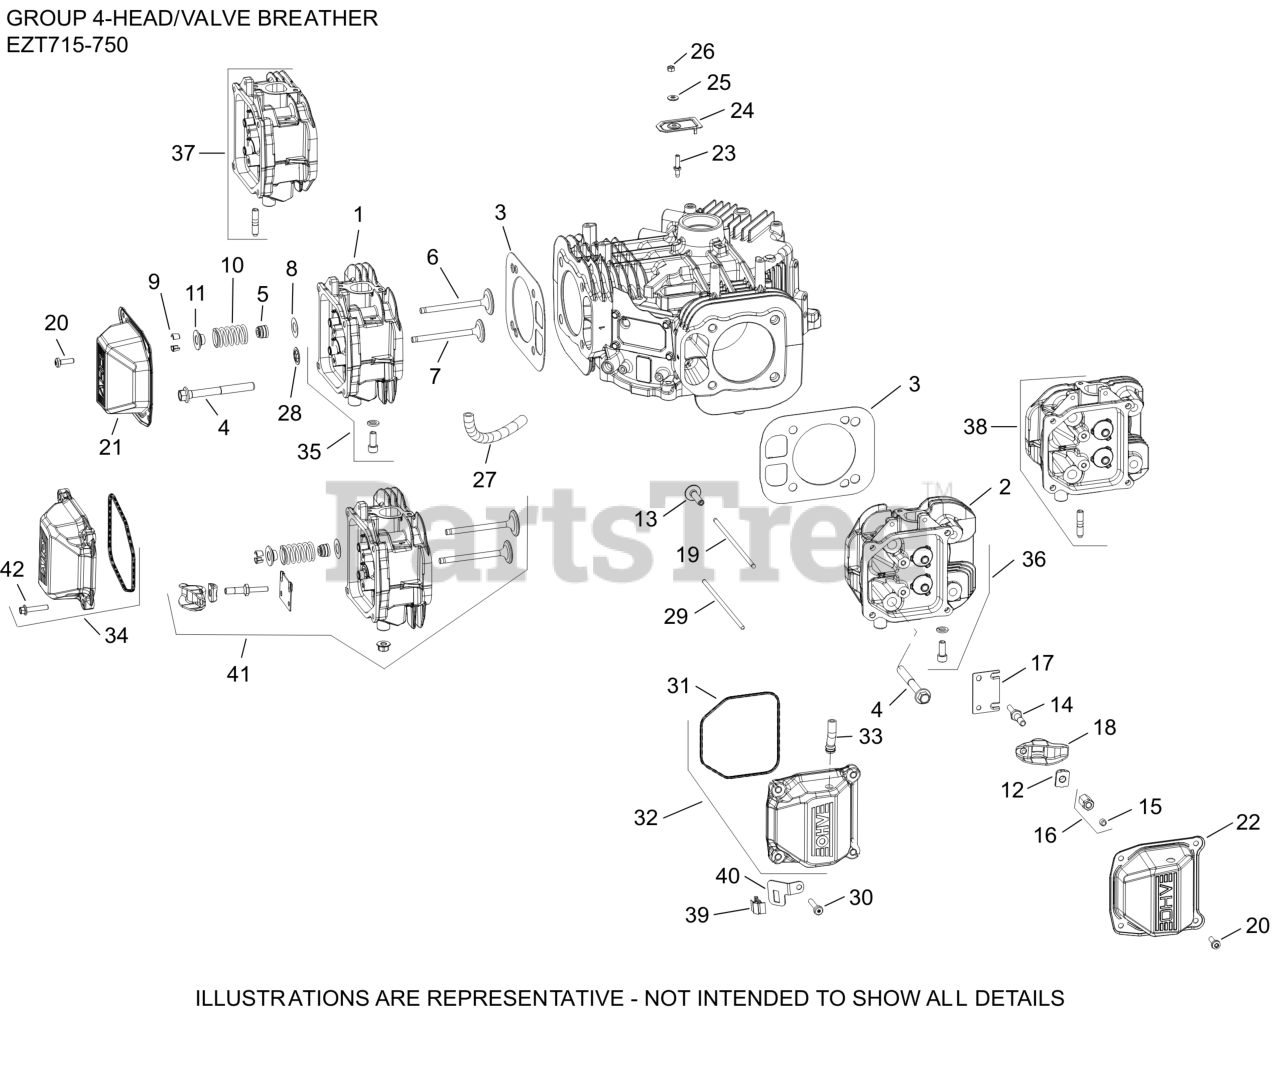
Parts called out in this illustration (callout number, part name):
3	KIT, GASKET CYLINDER HEAD
5	SEAL, VALVE BAND
7	VALVE, EXHAUST
7	VALVE, EXHAUST (.25)
8	SPACER (.010")
9	KIT, RETAINER
10	SPRING VALVE
11	CAP, VALVE SPRING
12	PIVOT, ROCKER ARM
14	STUD, ROCKER
15	SCREW, SET
16	HEX NUT ASSEMBLY
17	PLATE, GUIDE
18	ARM, ROCKER
19	ROD, PUSH
24	COVER, BREATHER REED
25	WASHER, SEALING
26	NUT, LOCK M5X.8
27	HOSE, BREATHER
28	RETAINER, VALVE GUIDE (KM)
31	O-RING (YELLOW), VALVE CO
32	KIT,BREATHER VALVE COVER (PLASTIC)
33	HOSE, FP-USE 32 326 07-S(PLASTIC COVERS)
34	KIT, VALVE COVER-PLAIN (PLASTIC)
36	KIT, HEAD #2 AND HARDWARE-(#1675521S)
41	KIT, CYLINDER HEAD #1
NI	VALVE, INTAKE (STD)
NI	VALVE, INTAKE (.25)-(#DSC)
NI	SCREW, HEX FLANGE M10 X 1.5-6g X 90mm
NI	SCREW, HEX FLANGE (M6 X 31.625 DOG PT)
